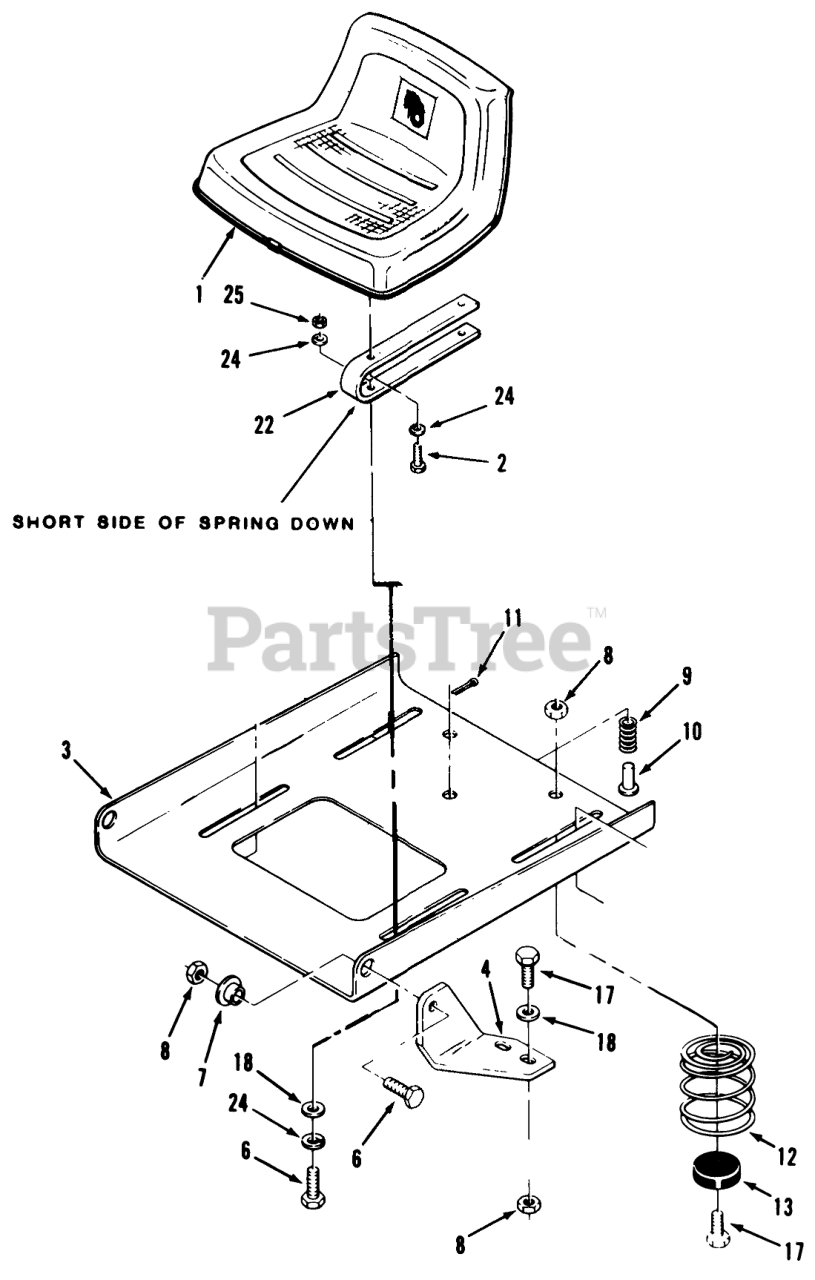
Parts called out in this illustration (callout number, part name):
2	SCREW-HH
3	PLATE-SEAT PIVOT B
4	BRACKET-PIVOT L.H B
6	SCREW-HH
7	NUT-LOCK, NI
8	NUT-LOCK, NI
9	SPRING-SEAT SWITCH
11	PIN-COTTER
12	SPRING
13	BUMPER
17	SCREW-HH
18	WASHER-PLAIN
22	SPRING
24	WASHER-LOCK
25	NUT-HEX
